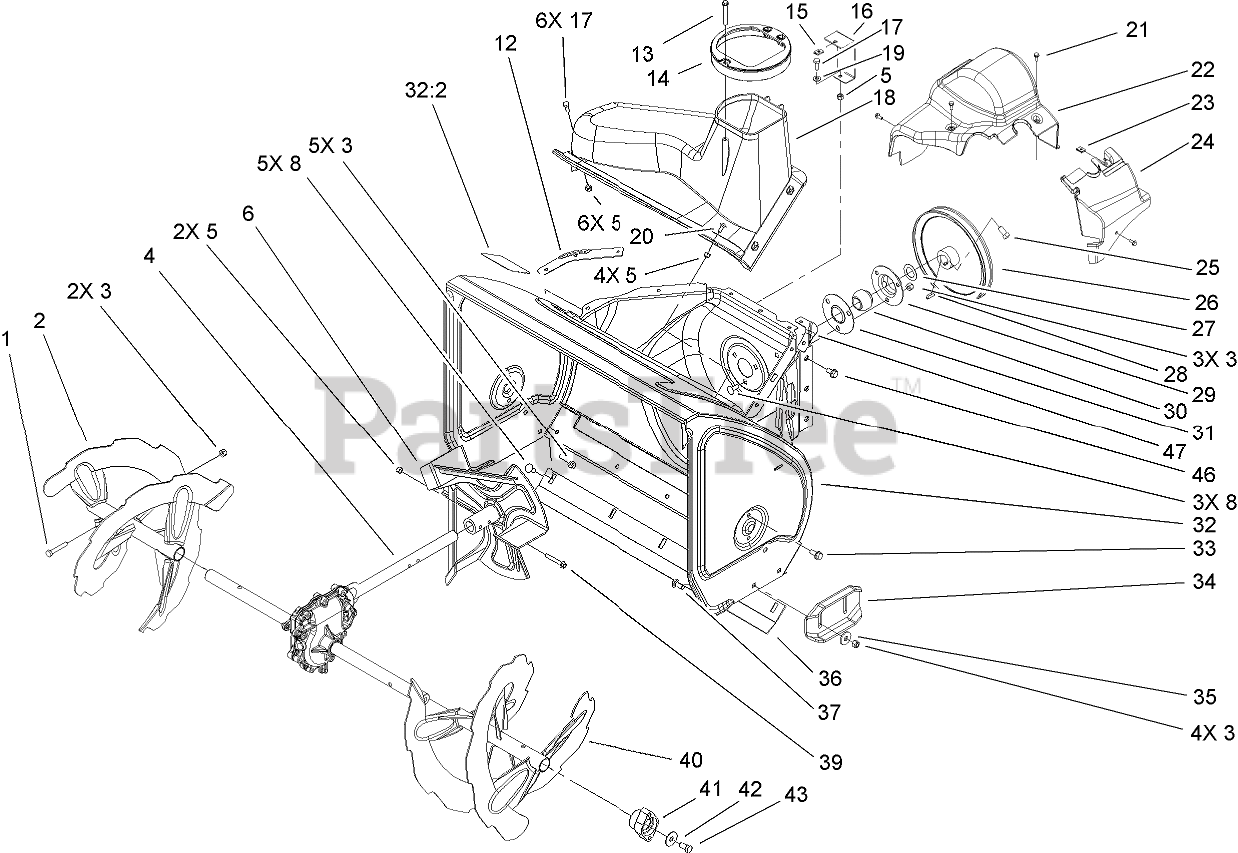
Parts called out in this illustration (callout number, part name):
1	SCREW-HH
2	RH AUGER ASM
3	NUT-LOCK, NI
4	26 INCH AUGER GEARCASE ASM
5	NUT-LOCK, NI
6	IMPELLER ASM
8	SCREW-CARR
12	SEAL-FLANGE, COVER
13	SCREW-PLASTITE
14	GUIDE-CHUTE
15	NUT-SPEED, U-TYPE
16	BRACKET-COVER, CLIP NUT
17	SCREW-HH
19	WASHER-FLAT
20	BOLT-CARR
21	SCREW-HWH
22	COVER-BELT
23	NUT-SPEED
24	COVER-EXTENSION, BELT
25	SCREW-SET, SQH
26	PULLEY-IMPELLER
27	WASHER-THRUST
28	KEY-WOODRUFF
29	FLANGE-CUP, BEARING
30	BEARING-BALL
31	FLANGE-CUP, BEARING
32	HOUSING-AUGER, 26 INCH
32:2	DECAL-WARNING, AUGER
33	SCREW-HWHTF
35	WASHER
36	SCRAPER-FIXED
37	SCREW-CARR
39	SCREW-HHF
40	LH AUGER ASM
41	BEARING-AUGER
42	WASHER
43	SCREW-HH
46	SCREW-HWHTF
